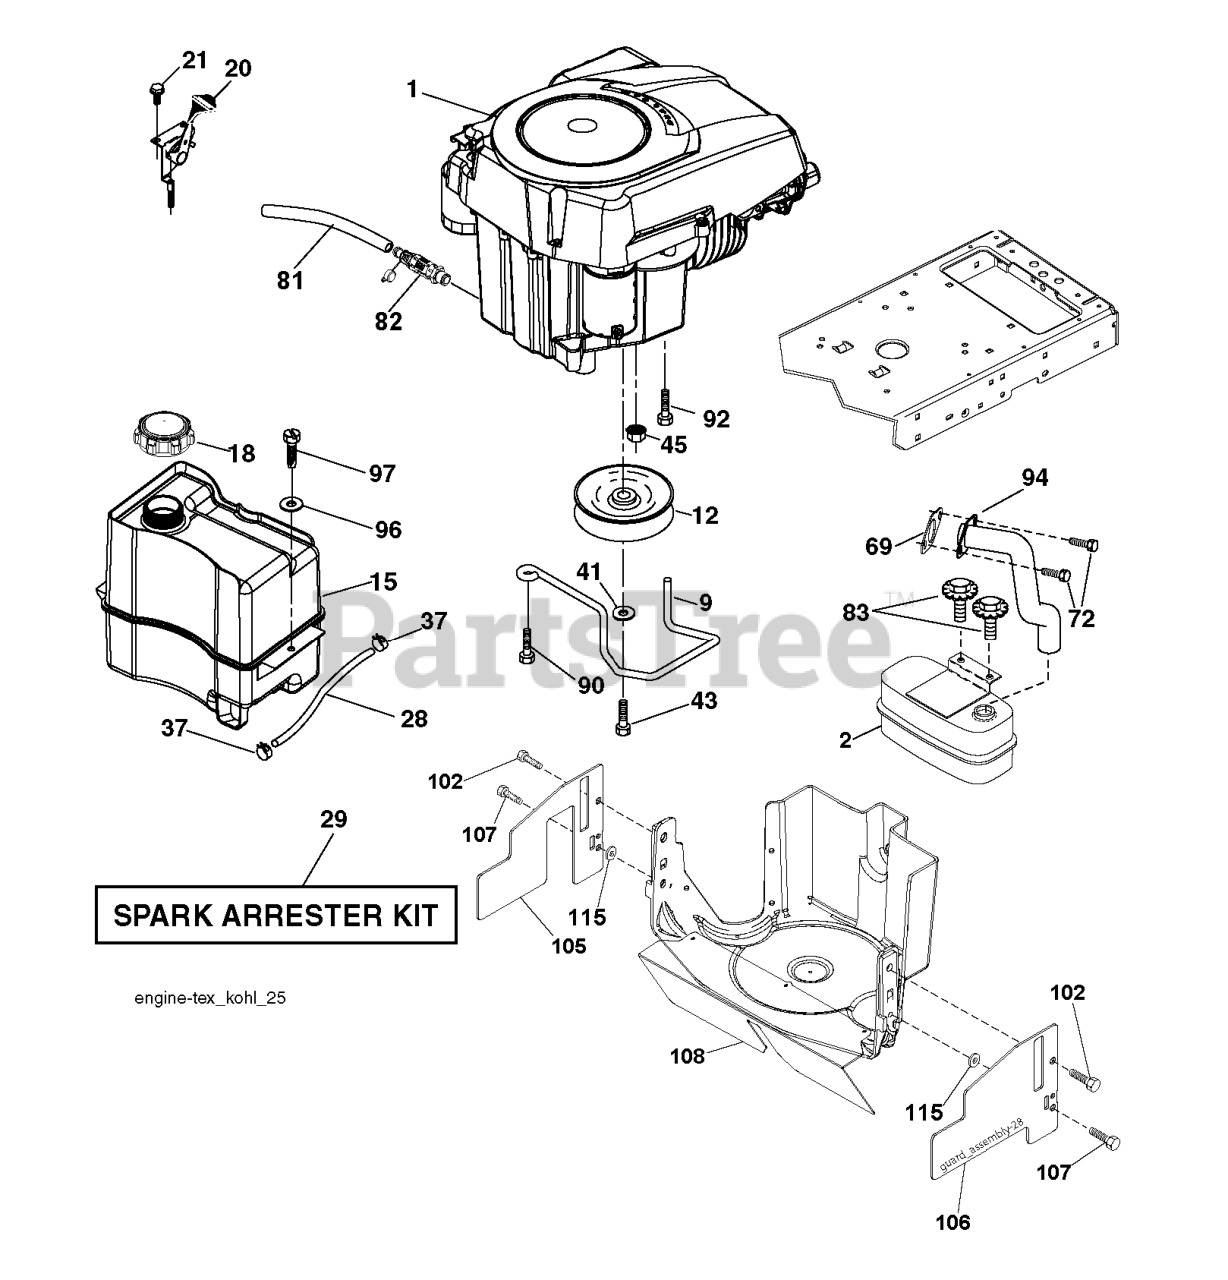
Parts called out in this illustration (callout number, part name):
2	MUFFLER.SINGLE.CYL.KOHL/B&S
9	KEEPER.BELT.ENGINE.3.25 (3 2)
12	PULLEY ENGINE
15	RP TANK FUEL FRT 1.5 GAL
18	CAP.FUEL.2.25"VENTED"
20	CONTROL.TH/CK.C.
21	SCREW.#10 X 0.750.BOS
28	LINE.FUEL.20
29	KIT.SPARK ARRESTOR 794945 B&S
37	HOSE CLAMP
41	LOCKWASHER
43	BOLT HEX 7/16-20X4-1/4"
45	NUT
69	GASKET.EXHAUST.KOHLER
72	SCREW.SOCKET HD.5/16-1
81	VALUE.OIL.DRAIN
82	PLUG DRAIN OIL EASY
83	BOLT.5/16-18UNCX3/4 W/SEMS.BLK
90	SCREW 3/8-16X1
92	SCREW 3/8-16X1
94	RP.TUBE.EXHAUST.KOHL.COURAGE
97	SCREW HEXWSHR 1/4-20X3/4
102	SCREW
105	SHIELD.SIDE.LH.3842"TEX FRENCH
106	SHIELD.SIDE.RH.3842"TEX FRENCH
107	SCREW.1/4-20X5/8
108	ENGINE COVER
115	PALNUT 1/4
